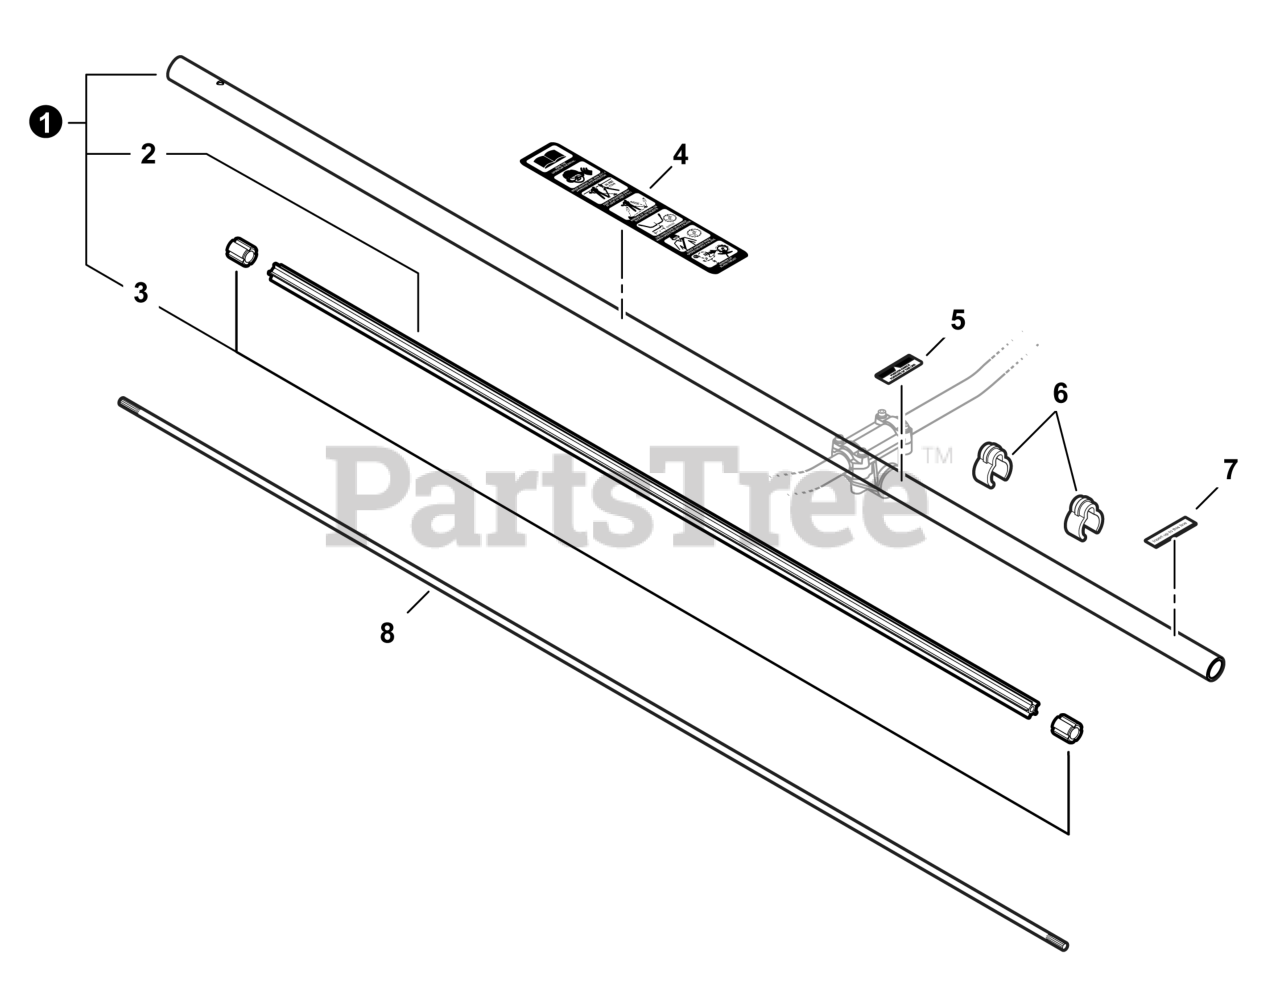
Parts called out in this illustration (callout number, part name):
1	MAIN PIPE ASSY
2	LINER, FLEXIBLE 21.6×1420
4	LABEL - CAUTION (BLADE CAPABLE)
5	LABEL - ALIGNMENT
6	CLIP, CABLE 25 MM
7	LABEL - ALIGNMENT
8	DRIVESHAFT - FLEXIBLE
